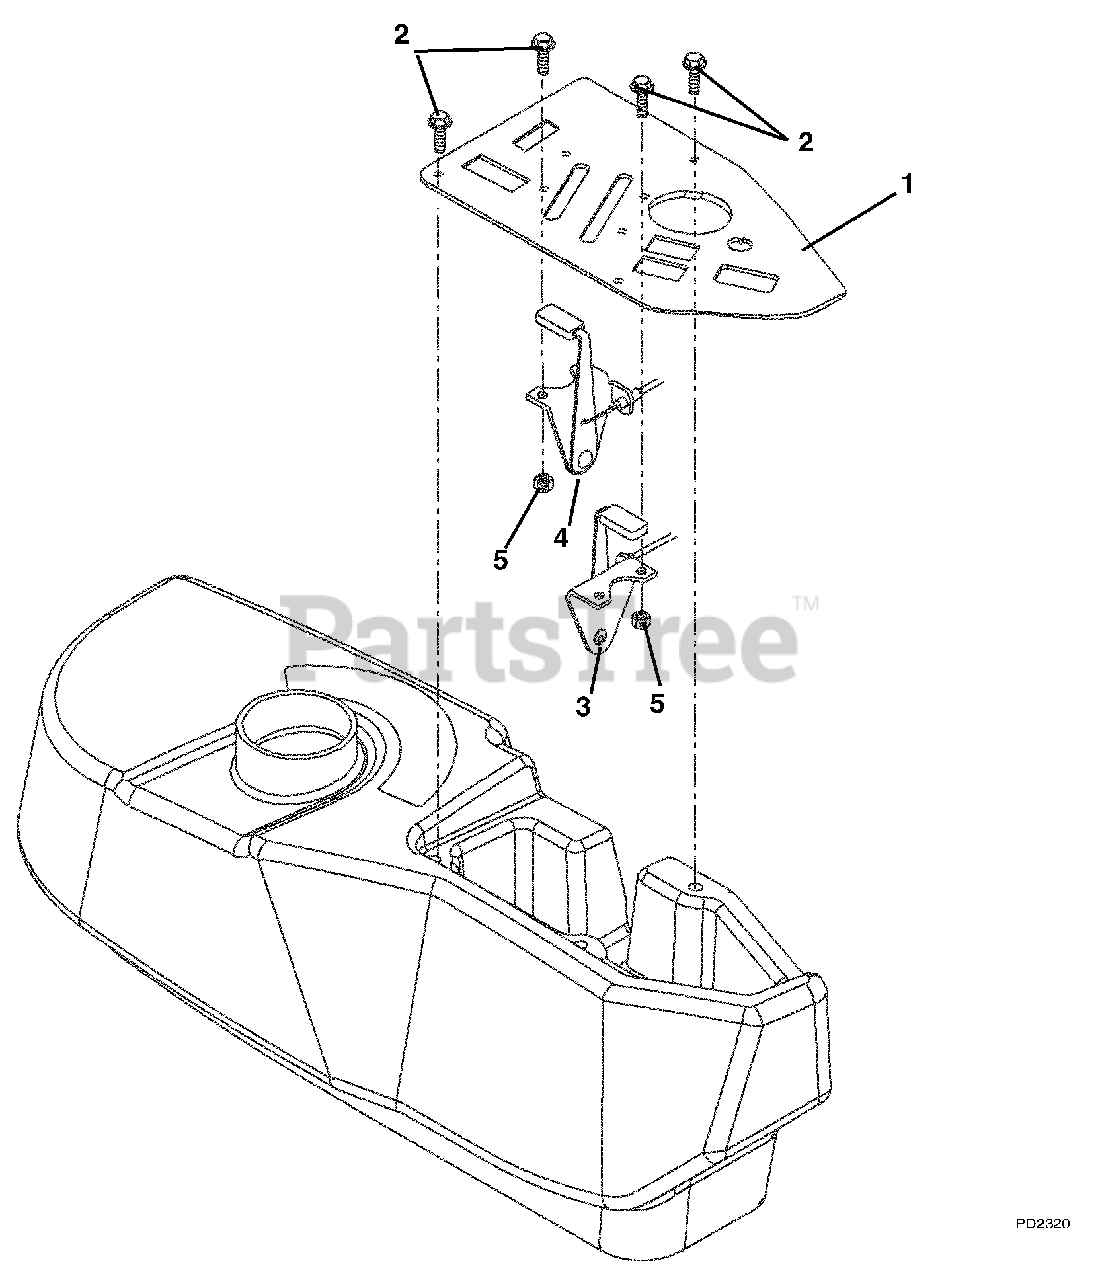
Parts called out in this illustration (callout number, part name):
1	Panel-Control
2	Screw-Machine 10-24 x .50 Hex Washer Head (036, 037)
2	Screw-Machine 10-24 x .50 Hex Washer Head (038, 039, 309)
3	Throttle, Control (036, 037)
3	Throttle, Control (038, 039, 309)
4	Choke Control
5	Nut-Locking-Nylon 10-24 With Insert (036, 037)
5	Nut-Locking-Nylon 10-24 With Insert (038, 039, 309)
